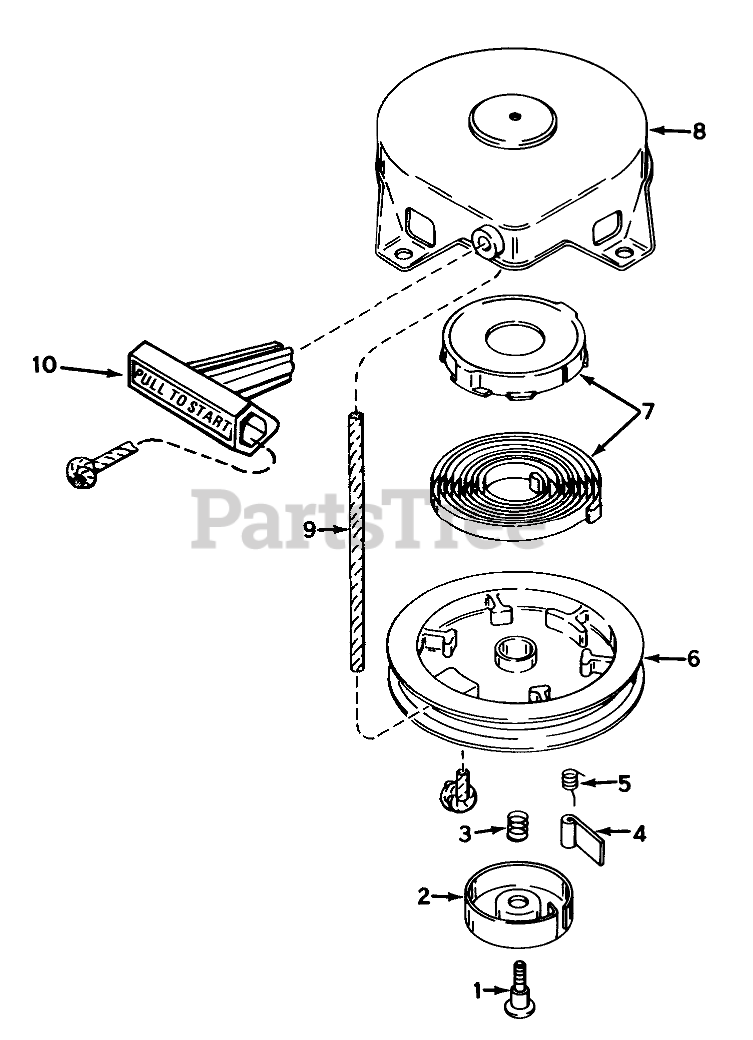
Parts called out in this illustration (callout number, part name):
2	Retainer
3	Spring-Brake
4	Dog-Starter
5	Spring-Dog
7	Spring & Keeper Assy
8	Housing-Starter
9	Rope-Starter (98 cut to length)
10	Handle-Starter
